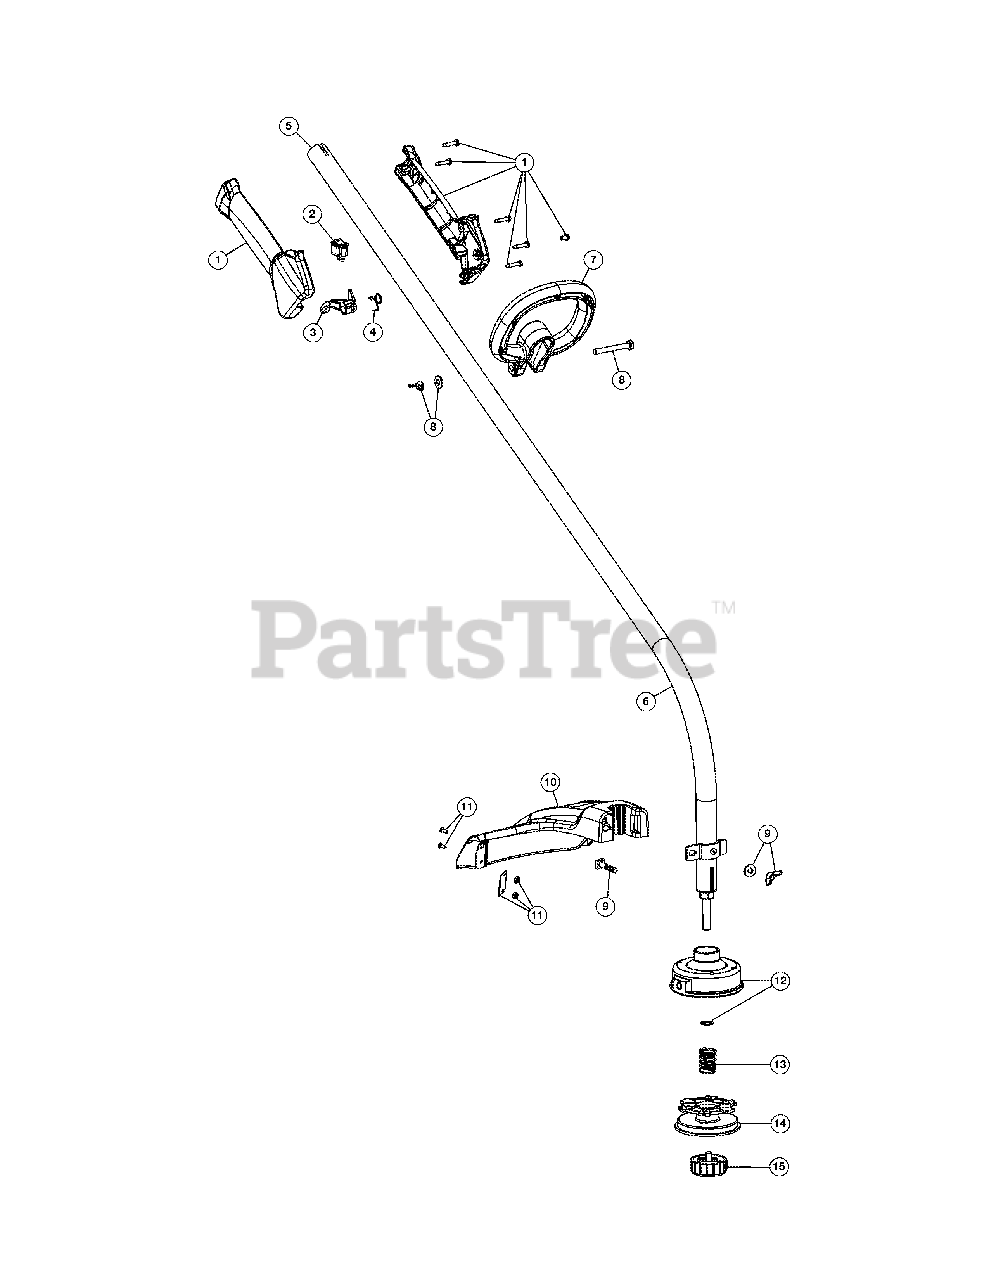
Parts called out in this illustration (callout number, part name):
1	Throttle Housing Assembly (includes 2-4)
3	Throttle Trigger
4	Throttle Trigger Spring
5	Flexible Drive Shaft
6	Drive Shaft Housing Assembly (includes 5)
7	D-Handle (includes 8)
8	D-Handle Hardware Assembly
9	Shield Mounting Hardware
10	Shield Assembly (includes 9 & 11)
11	Blade Assembly
12	Outer Spool w/Retainer
14	Inner Reel
15	Bump Head Knob Assembly
